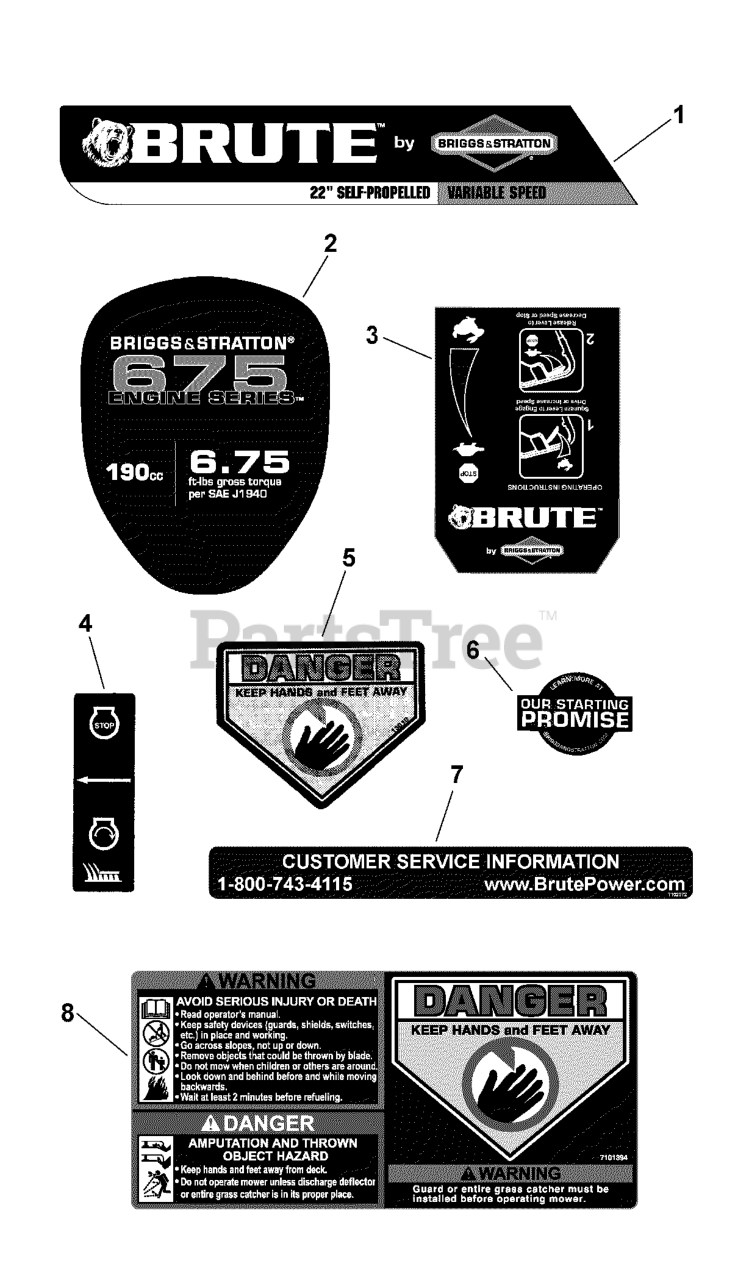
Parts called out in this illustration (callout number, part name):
1	DECAL, 22" Deck, Front Wheel Drive, Electric Start
2	DECAL, Engine, TP, Brute 675
3	DECAL, Control Head
4	DECAL, OPC Bail International Symbol
5	DECAL, Danger, Cut Finger
6	DECAL, Starting Promise
7	DECAL, Customer Service, Brute
8	DECAL, Warning, Rear Discharge Door
